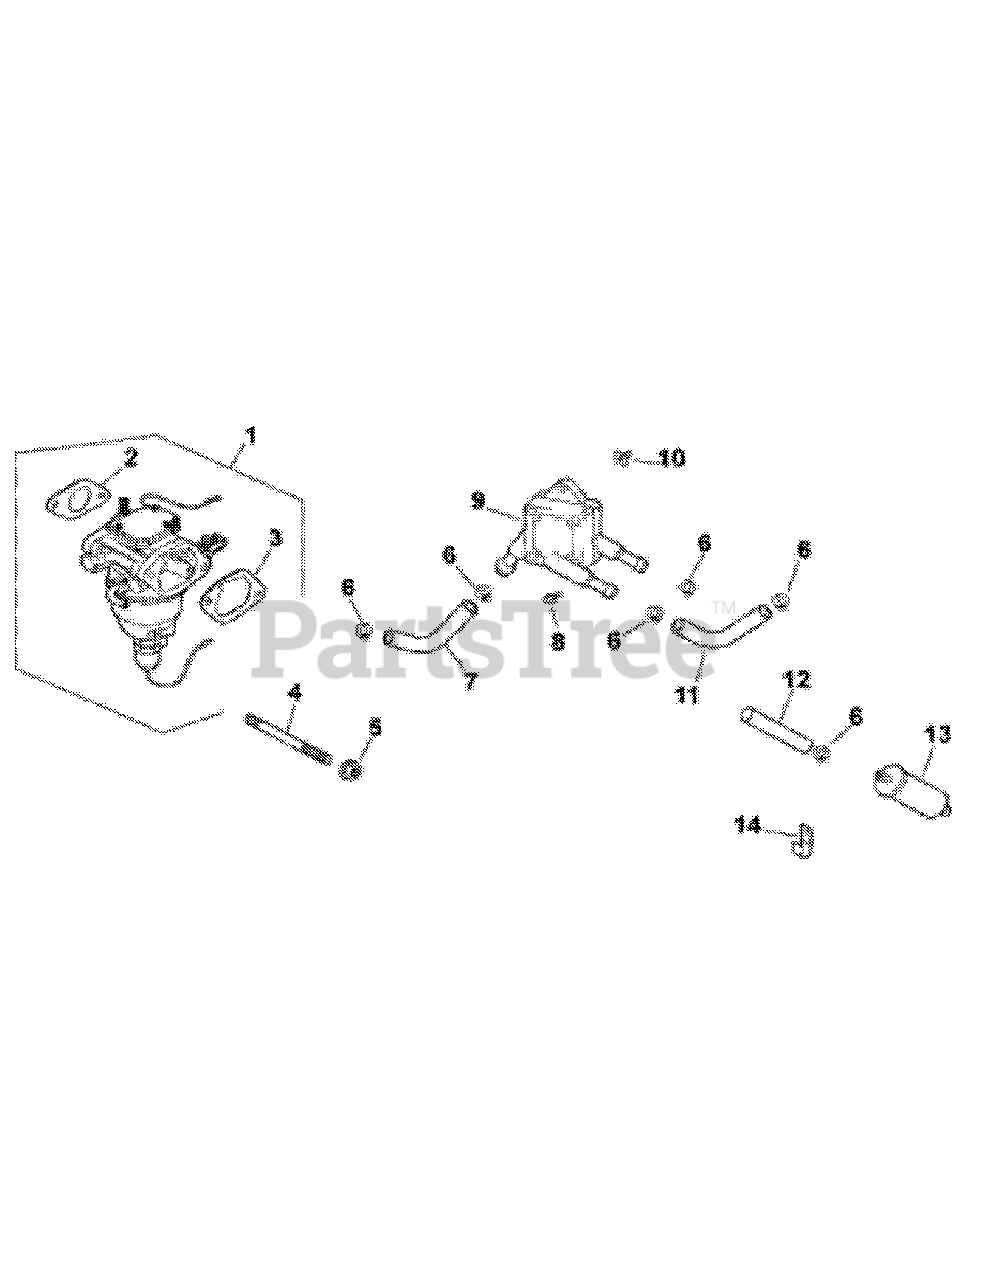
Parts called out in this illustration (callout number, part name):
1	Carburetor w/Accelerator Pump
2	Carburetor Gasket
3	Air Cleaner Base Gasket
5	Hex Flange Nut
6	Hose Clamp
8	Hex Cap Screw
10	Plastic Nut
13	Fuel Filter
